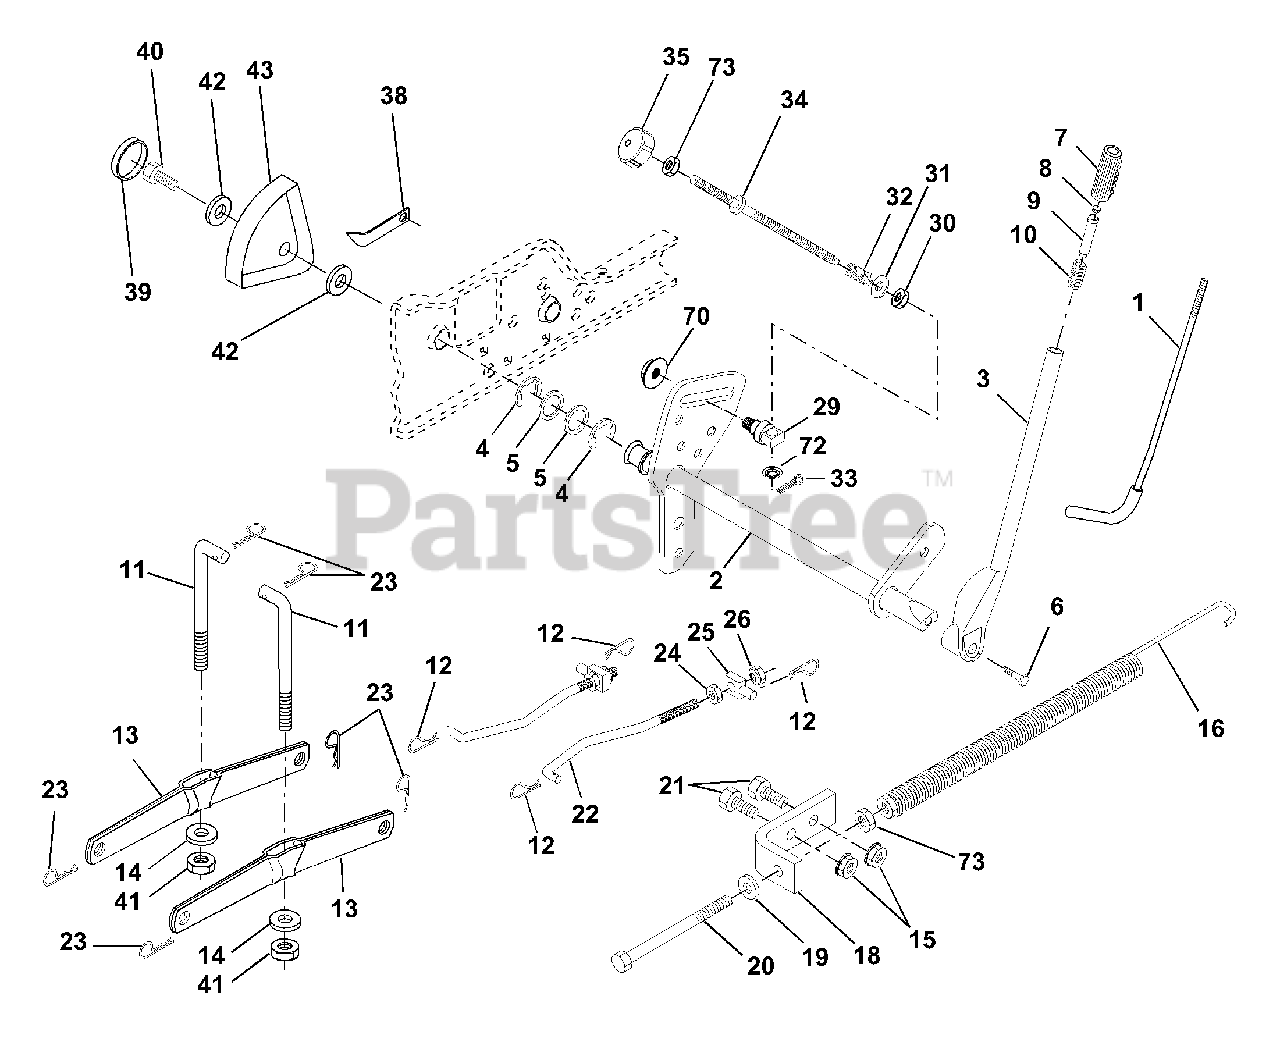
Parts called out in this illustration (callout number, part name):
1	Rod Asm., Lever
2	Shaft Asm., Lift Vgt
3	Lever Asm., Lift Rh
4	E-Ring Truarc #5133-87
5	Washer 29/32 x 1-1/4 x 16 Ga.
6	Bolt, Fin Hex 3/8-16 x 1-1/2
7	Grip, Handle
8	Button, Plunger
9	Plunger, Lever Lift
10	Spring 2-1/8"
11	Link Lift
12	Retainer, Spring
13	Arm, Suspension Vgt
15	Nut, Crownlock 3/8-16
16	Spring Asm., Assist Lift
17	Nut, Hex Jam 3/8-16 Unc
18	Bracket, Spring Assist
19	Washer 13/32 x 13/16 x 16 Ga.
20	Bolt, Adjust Spring Assist
21	Bolt, Fin Hex 3/8-16 x 1
22	Link, Front
23	Retainer, Spring
24	Nut, Jam Hex 1/2-13 Unc
25	Trunnion
26	Nut, Lock W/Wsh 1/2-13 Unc
29	Trunnion 1nfin Height
30	Nut, Special
31	Washer 13/32 x 5/8 x 16 Ga.
32	Spring, Compression Inf Hgt
33	Pin, Cotter 3/32 x 1/2
34	Rod, Adj Lift
35	Knob, Inf 3/8-16 Unc
38	Pointer Height Indicator
39	Plug, Hole Blk. 1.485/1.515 Dia.
40	Screw 5/16-18 x 1
41	Nut, Crownlock 3/8-24
42	Washer 11/32 x 1-1/2 x 10 Ga.
43	Scale, Indicator Height
70	Nut Hex Flange Lock
72	Nut Push Phos & Oil
